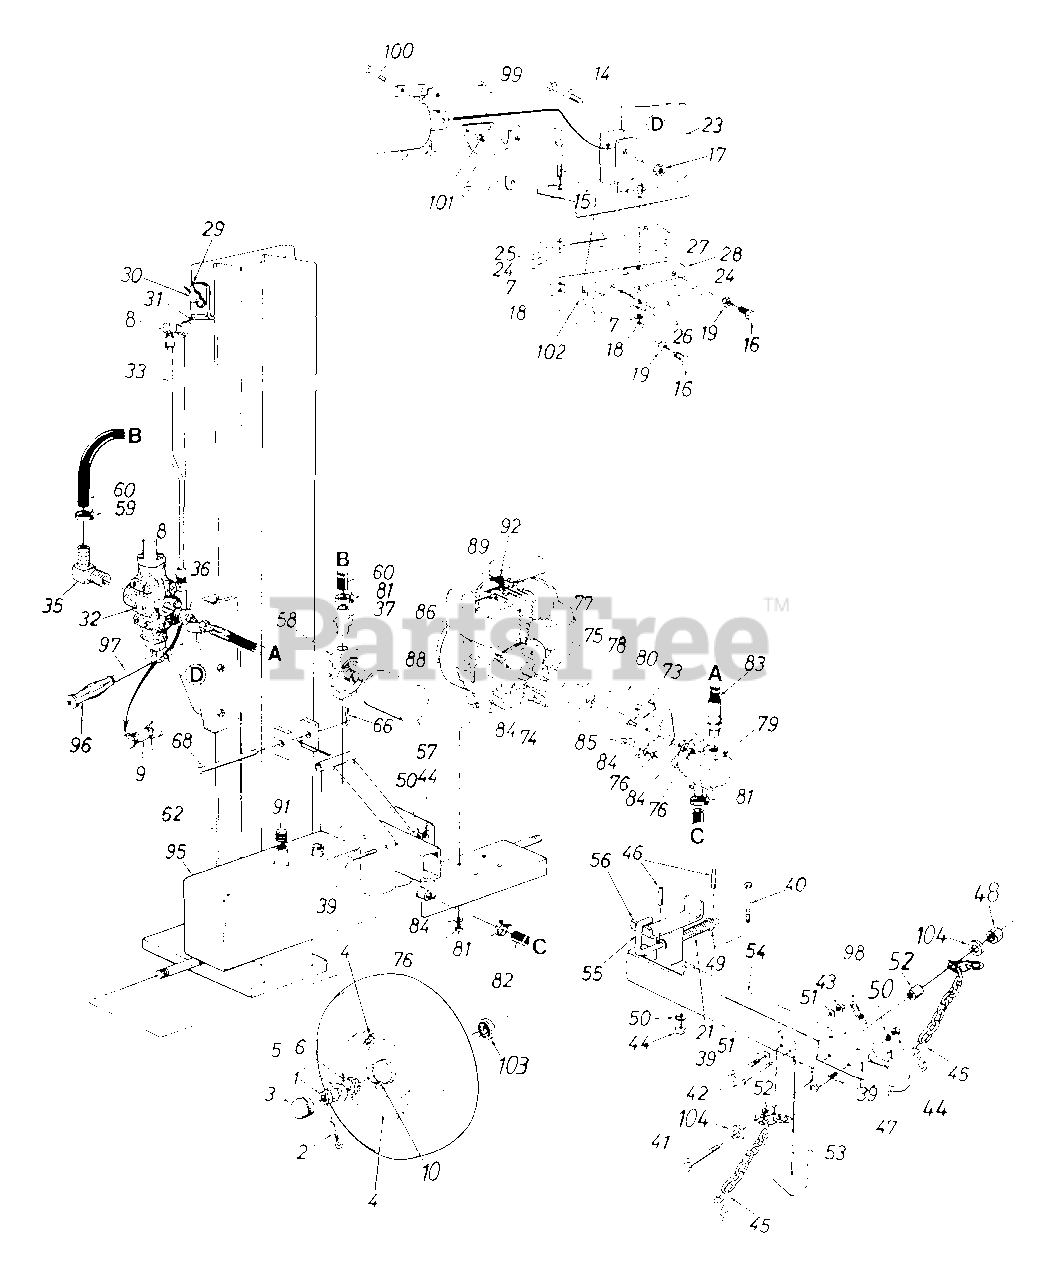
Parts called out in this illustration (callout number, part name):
1	Slotted Nut 3/4-16 Thd.
2	Cotter pin 5/32" Dia.
3	Hub Cap
5	Fl-Wash. .76" I.D. x 1.5" O.D.
6	Bearing Cone
7	L-Wash. 1/2" I.D.
8	90° Solid Male Adaptor
9	Pipe Nipple 1/2 NPT
10	Bearing Cup
14	Hex Bolt 1/2-20 x 3" Lg. (Grade 8)
15	Hex Bolt 1/2-20 x 2.75" Lg. (Grade 8)
16	Hex Bolt 3/8-24 x 1.5" Lg.
17	Hex L-Nut 1/2-20 Thd.
18	Hex Nut 1/2-20 Thd.
19	Hex Jam Nut 3/8-24 Thd. (Grade 5)
21	Comp. Spring 4" Lg.
29	External Cotter Pin
30	Cylinder Mounting Pin
31	Hydraulic Cylinder
33	Metal Pressure Tube
35	Return Elbow
36	Adapter
37	3/4" Hose Barb.
39	Hex Bolt 3/8-16 x 3" Lg. (Grade 8)
40	Hex Bolt 3/8-16 x 4" Lg.
41	Hex Bolt 3/8-16 x 4" Lg. (Grade 5)
42	Clevis Pin 5/16 x 2.5" Lg.
43	Hex L-Nut 3/8-16 Thd.
44	Hex Nut 3/8-16 Thd.
45	Chain - Tow Hitch
46	Roll Pin
47	Hitch Coupler
48	Hex Ctr. L-Nut 3/8-16 Thd.
49	Fl-Wash. .635" I.D. x .93" O.D.
50	L-Wash. 3/8" I.D.
51	Fl-Wash. .406" I.D. x .75" O.D.
52	Spacer .27" Lg.
55	Locking Rod
57	Filter Element
58	Filter Head
59	Adj. Hose Clamp
60	Return Hose 3/4" I.D. x 44" Lg.
62	Vertical Beam Ass'y.
66	Cotter Pin 1/8" Dia.
68	Hinge Pin 1/2 x 4.8" Lg.
73	Hex Bolt 5/16-24 x 1" Lg.
75	Hex Bolt 5/16-24 x 5" Lg.
76	Hex Nut 5/16-24 Thd.
77	Sq.-Key 3/16" x .75"
78	Flexible Coupling
79	Two Volume Pump
80	Coupling Shield
81	Hose Clamp 5/8"
82	Suction Hose 3/4" I.D. x 22" Lg.
83	High Pressure Hydraulic Hose 62"
84	L-Wash. 5/16" I.D."
88	Hex Bolt 5/16-24 x 1.75" Lg.
89	Engine
91	L-Vent Pipe Plug
92	Spark Plug Boot
95	Tank Ass'y.
96	Grip
97	Control Handle
98	Spring 9 in
101	Hex L-Nut 3/8-16 Thd.
102	Spacer 1/2" I.D. x .68" Lg.
103	Bearing Seal Only
104	Fl-Wash. 3/8" I.D. x .87" O.D.
